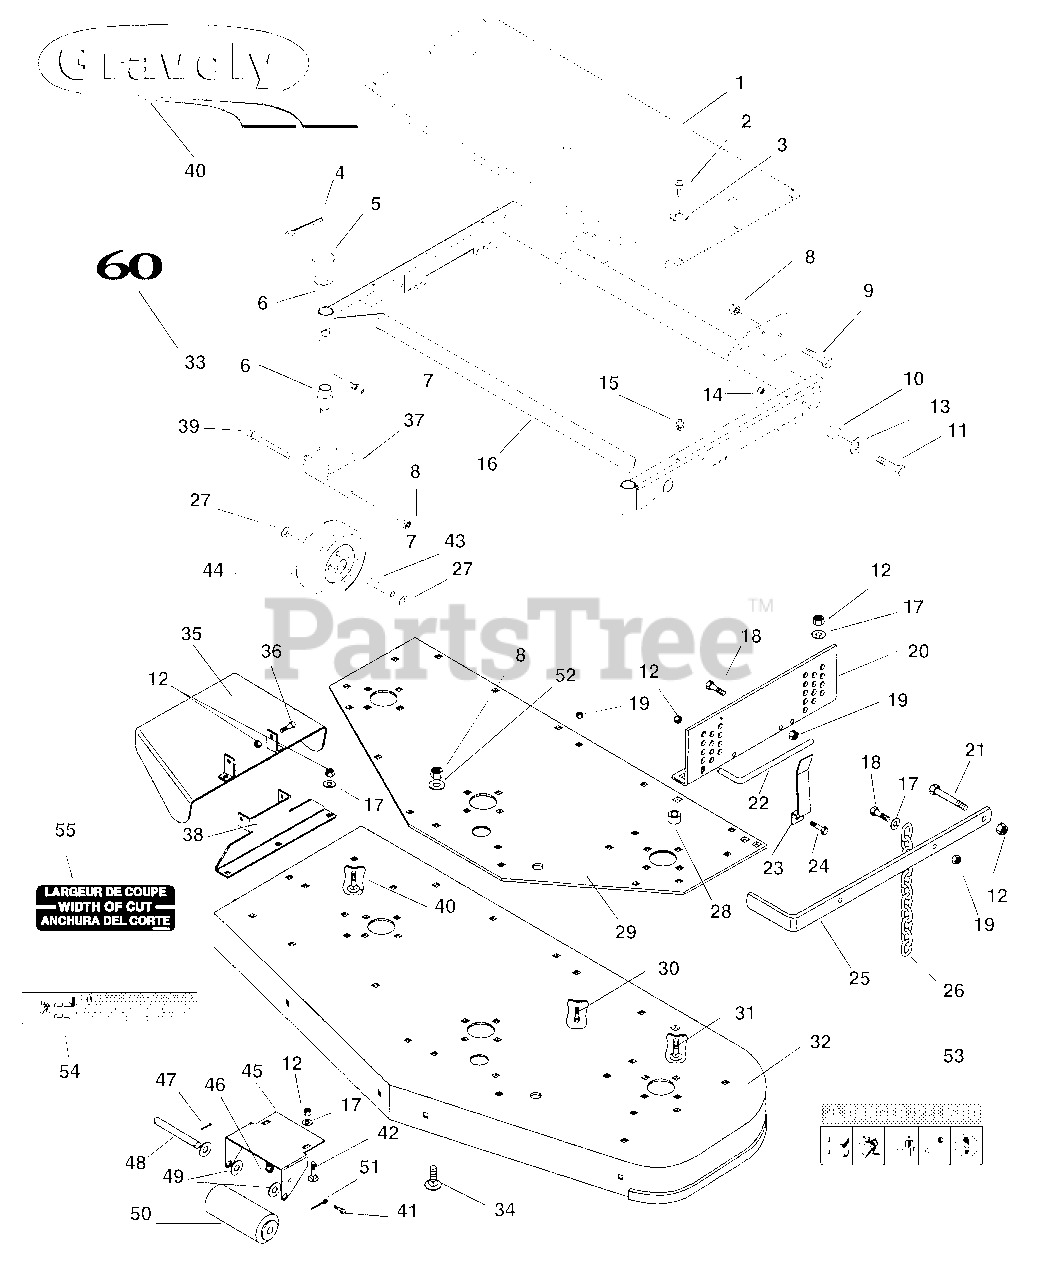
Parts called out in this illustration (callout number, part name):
1	Guard, Belt 60"
2	Screw-Tap .250-20 x .50
3	Washer-Flat-Steel .281 x .625 x .065
4	Pin-Cotter .188 x 1.500
5	Washer-Hardened-Thrust 1.002 x 1.552 x .030
6	Bushing-Flange 1.020 x 1.385 x .75 x 1.75
7	Fitting-Lube .25-28 x .256
8	Nut-Locking-Nylon .50-13 Grade 5
9	Bolt-Hex .50-13 x 1.50 Grade 5
10	Bushing .391 x .626 x .670
11	Bolt-Hex .38-16 x 1.50 Grade 5
12	Nut-Locking-Nylon .375-16 Grade 2
13	Washer-Flat-Steel .390 x 1.5 x .125
14	Nut-Locking-Nylon .375-16 w/ Insr Grade 2
15	Grommet, Plastic
16	Weldment, Mower Frame
17	Washer-Flat-Steel .406 x .812 x .065
18	Bolt-Hex .31-18 x 1.00 Grade 5
19	Nut-Locking-Nylon .312-18 Grade 2
20	Bracket, Mower Support Left Hand
20	Bracket, Mower Support Right Hand
21	Bolt-Hex .38-16 x 2.0 Grade 5
22	Pin, Mower Locking
23	Spring, Pin
24	Bolt-Hex .38-16 x .75 Grade 5
25	Bar, Lift
26	Chain, Height Adjuster
27	Washer-Hardened .760 x1.25 x .094
28	Bushing .406 x .750 x .188
29	Plate, 60" Support
30	Bolt-Hex .31-18 x .75 Grade 5
31	Bolt-Round Head Square Neck .38-16 x 1.25
32	Weldment, 60" Mower
33	Decal, 60"
34	Bolt-Round Head Square Neck .50-13 x 1.00
35	Weldment, Discharge Chute
36	Bolt-Hex .375-16 x 1.00 Grade 5
37	Weldment, Caster Fork
38	Bracket, Discharge
39	Bolt-Hex .50-13 x 5.50
40	Decal, Gravely Logo
41	Bolt-Hex .25-20 x .75 Grade 5
42	Bolt-Round Head Square Neck .38-16 x 1.0
43	Bearing, Gauge Wheel .750 x .532 x 3.97
44	Wheel 9 x 3.50
45	Bracket, Roller Right Hand
46	Nut-Locking-Nylon .250-20 Grade 2
47	Pin-Cotter .25 x 1.00
48	Shaft, Center Roller
49	Washer-Flat-Steel .656 x 1.312 x .095
50	Roller, Gauge
51	Pin-Cotter .250 x 2.00
52	Washer-Flat-Steel .50 x 1.25x .083
53	Decal, Mower Pan Head Danger
54	Decal, Warning
55	Decal, Width of Cut
